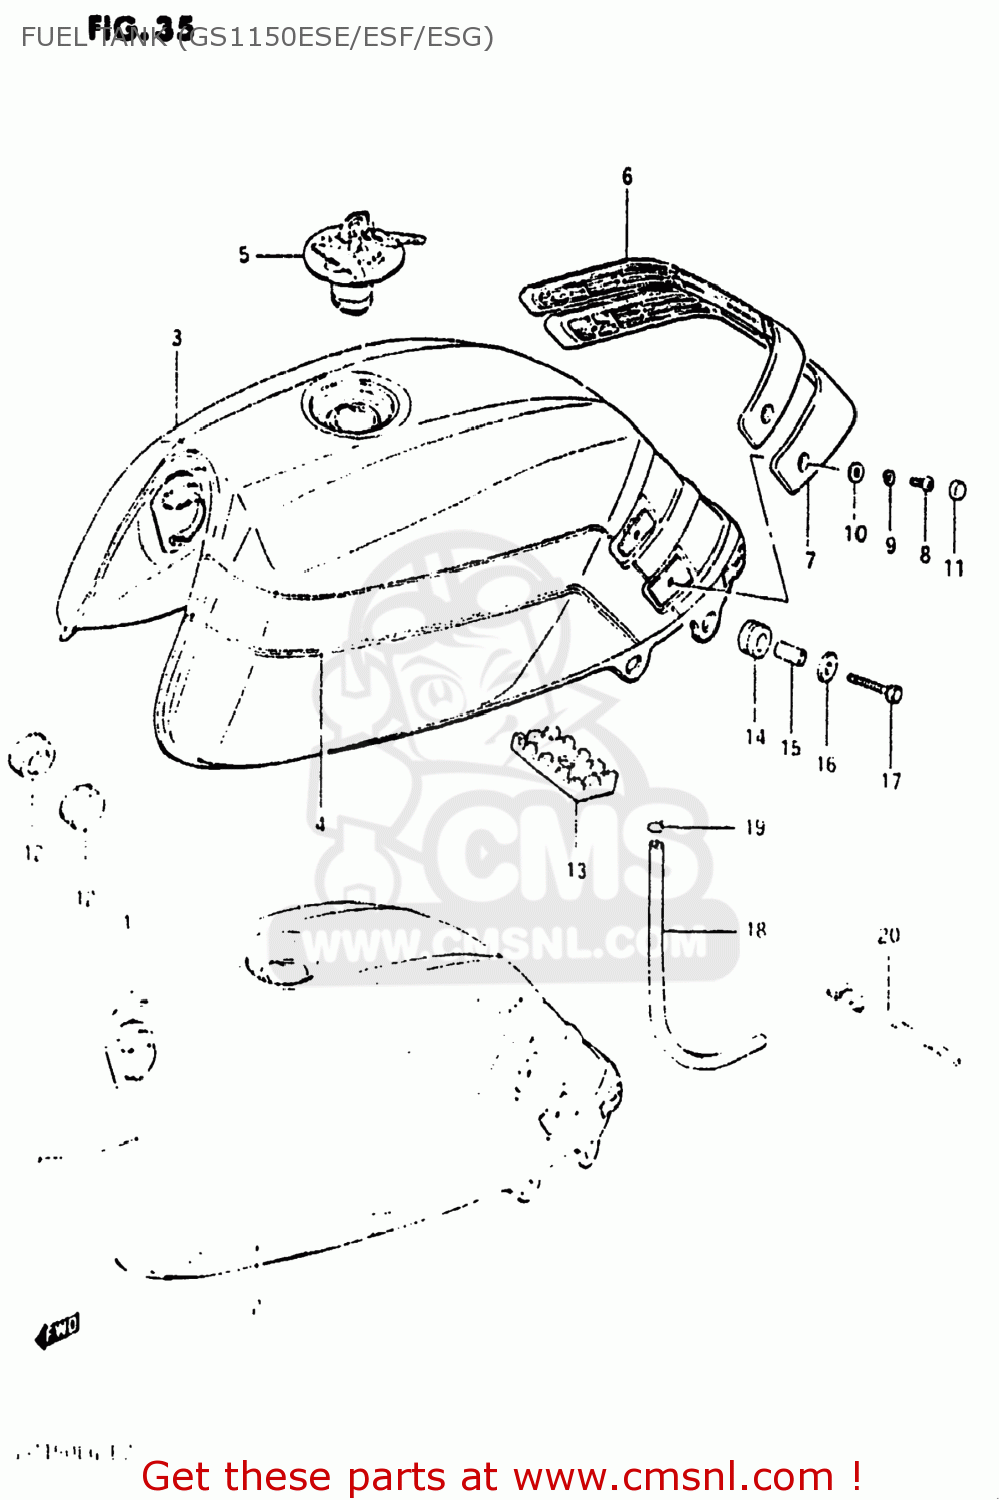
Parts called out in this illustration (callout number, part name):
1	TANK ASSEMBLY,FUEL
2	TAPE SET,FUEL TANK
3	TANK ASSEMBLY,FUEL
4	TAPE SET,FUEL TANK
5	CAP SET,FUEL TANK
6	KNEE GRIP,FUEL TANK,UPPER
7	KNEE GRIP,FUEL TANK,LOWER
8	SCREW
9	LOCK WASHER
10	WASHER
11	CAP,KNEE GRIP
12	CUSHION
13	CUSHION,FUEL TANK CTR
14	CUSHION
15	SPACER (6.4X9X20)
16	WASHER (6.5X29X1.6)
19	CLIP
20	CLAMP(L:187)
27	BOLT 6X30
28	HOSE,FUEL
